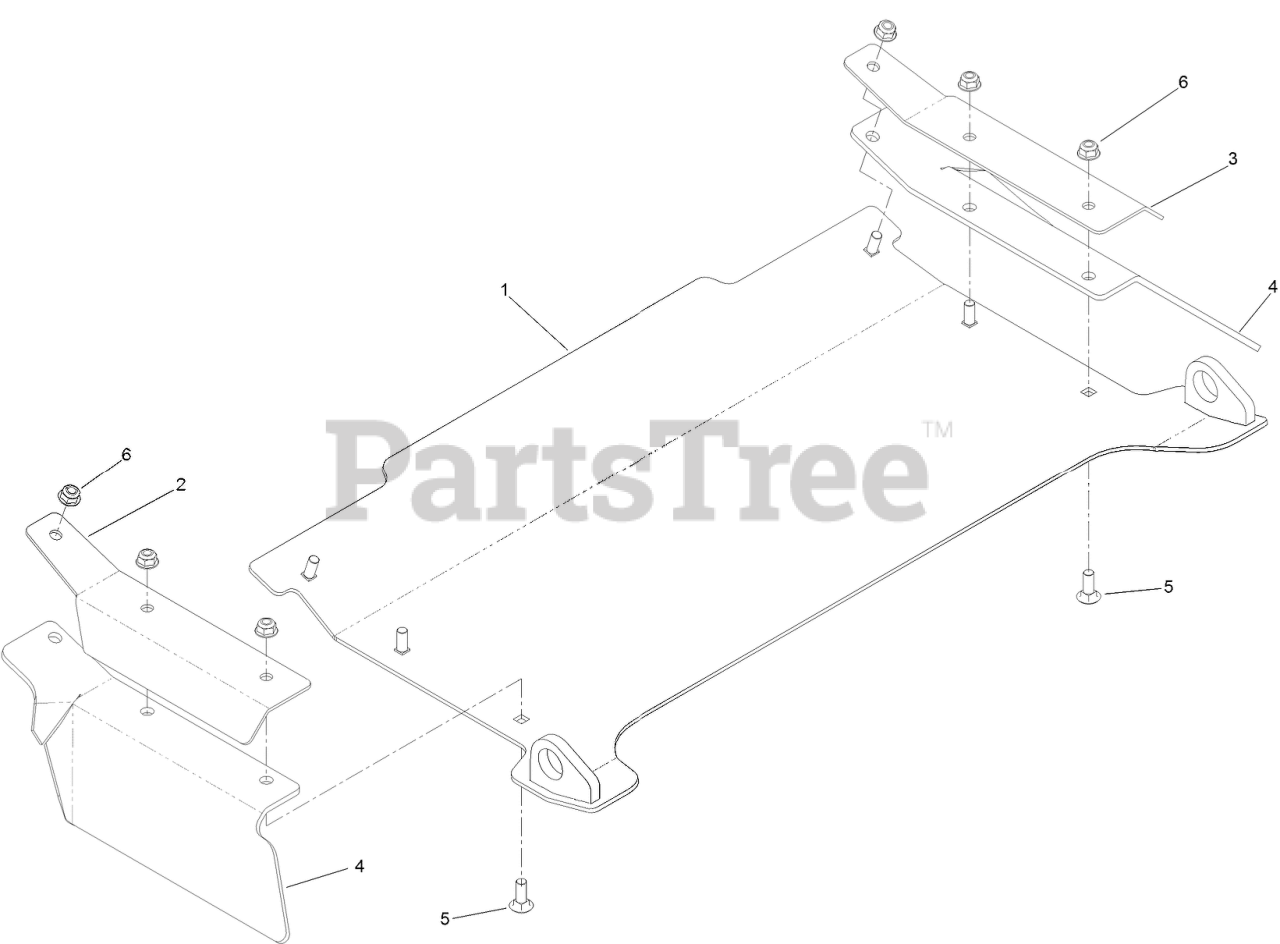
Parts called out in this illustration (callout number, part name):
1	DISCHARGE TUNNEL ASM
2	BRACKET-FLAP, LH
3	BRACKET-FLAP, RH
4	FLAP-RUBBER
5	SCREW-CARR
6	NUT-HF, NI
